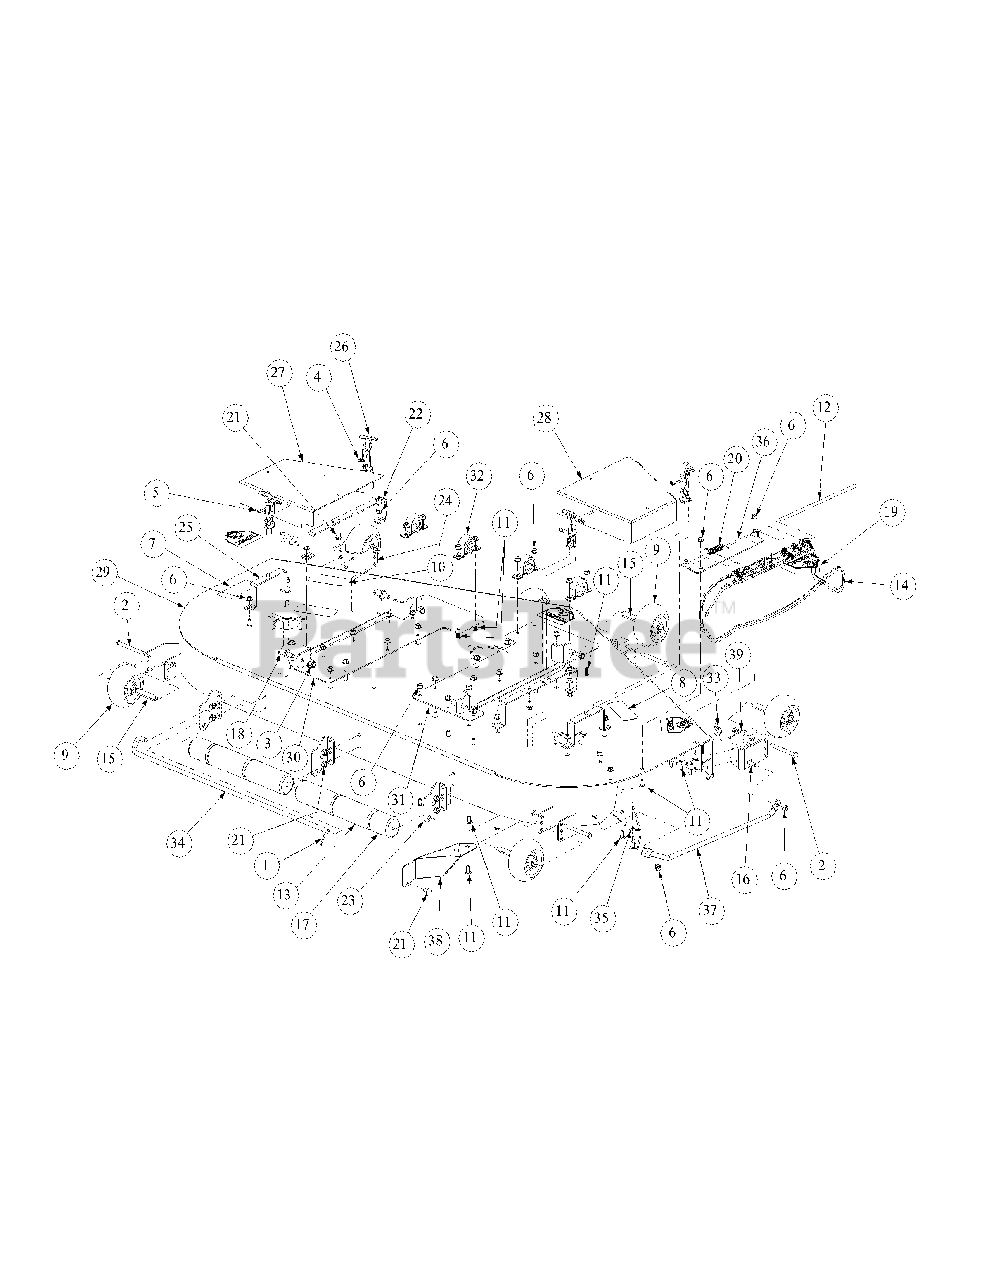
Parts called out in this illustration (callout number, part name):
1	Cotter Pin, .125 Dia. x 1.0
2	Hex Cap Screw, 3/8-16, 3.75
3	Lock Nut, Nylon Insert, 1/2-13
4	Lock Nut, Nylon Insert, #10-32
5	Phillips Head Screw, #10-32 x 1/2
6	Flange Lock Hex Nut, 3/8-16
7	Decal, Rotating Blade
8	Decal, Warning Shield Missing
9	Complete Wheel, 5.00 Dia.
10	Command Cut Large
11	Carriage Bolt, 3/8-16 x .75 Lg.
12	Pin, .375 x 14.06
13	Front Roller
14	Chute Deflector
15	Wheel Spacer
16	Carriage Bolt, 3/8-16 x 1
17	Grass Catcher Roller
18	Pin, 5/8 Dia. x 1.2 Lg.
19	Decal, Danger Hand and Feet
20	Torsion Spring, 0.4ID x 2.16Lg
21	Hex Index Washer Screw, 3/8-16, .5
22	Belt Cover Support
23	Deck Roller Mount Bracket
24	Anti-Scalp Wheel Front Mount Bracket
25	Outer Belt Cover Support Assembly
26	T-Handle Latch Draw
27	Left Hand Deck Belt Cover Weldment
28	Right Hand Deck Belt Cover Weldment
29	72" Deck Assembly
30	Left Hand Deck Weldment Bracket
31	Right Hand Deck Weldment Bracket
32	Pillow Block
33	Decal, 72"
34	Roller Pin
35	Chute Bracket
36	Chute Bracket
37	Finger Guard
38	Discharge Baffle WEldment
39	Anti-Scalp Wheel Front Mount Bracket
